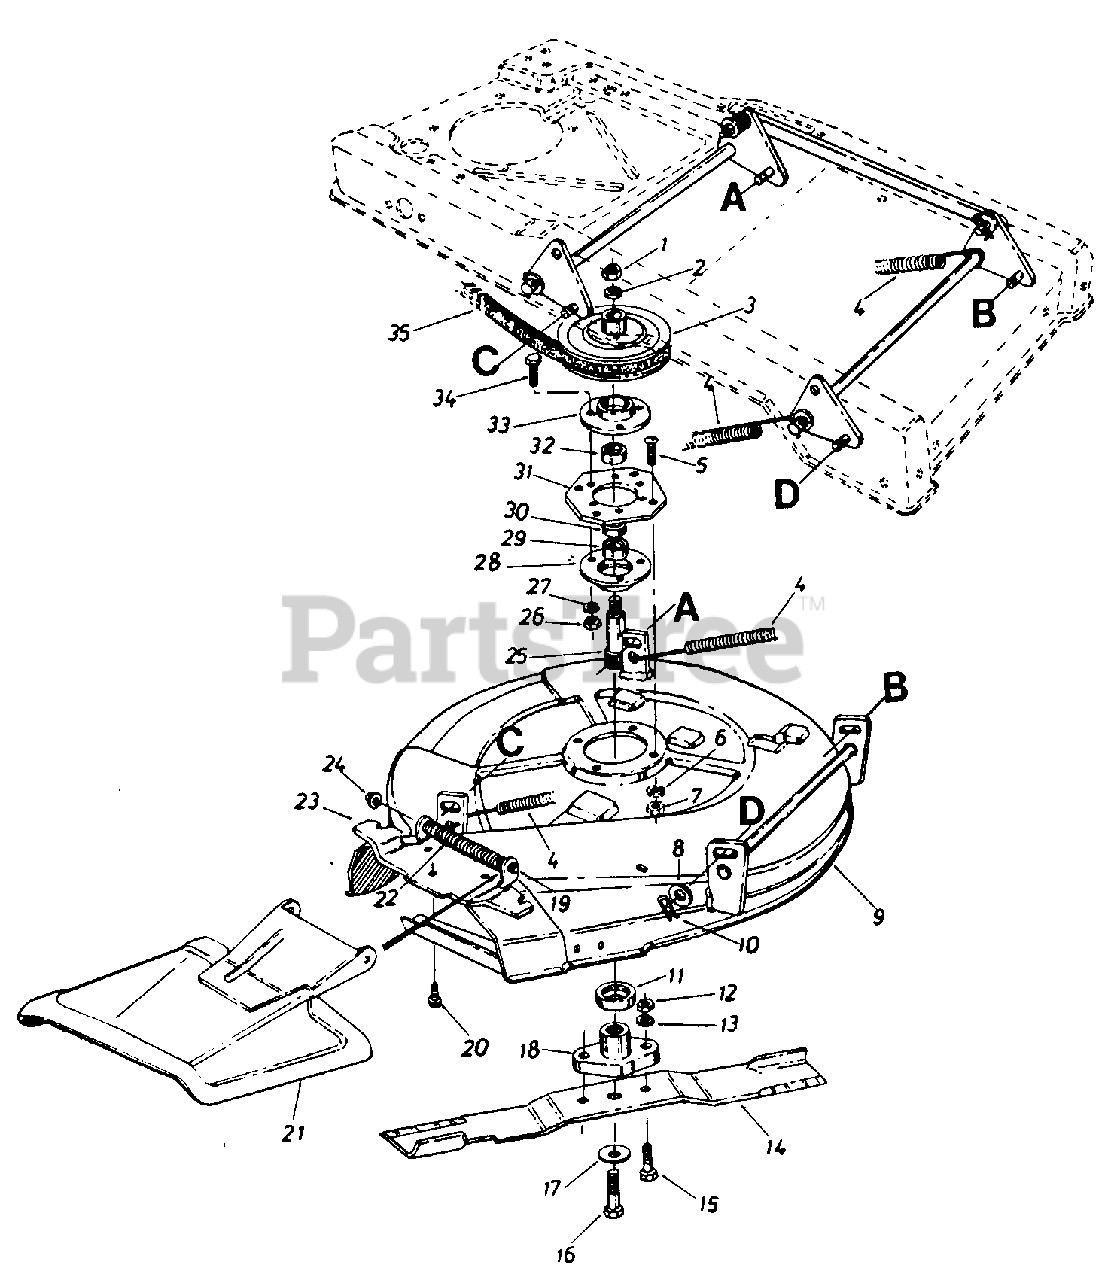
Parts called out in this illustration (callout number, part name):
1	NUT-HEX JAM 5/8-18
2	WASHER-BELL
4	SPRING-EXTENSION
5	SCREW-HEX 5/16-18 X .75
6	WASHER-LOCK-5/16
7	NUT-HEX 5/16-18
8	WASHER-FL .510 X .995 X .060
9	DECK ASSEMBLY-26IN
10	PIN-INTERN COT-1/2 DIA
11	SHIELD-BRG
12	NUT-5/16-24
13	WASHER-LOCK-5/16
14	BLADE-26IN
15	SCREW-HEX SPECIAL 5/16-24X1.0
16	BOLT-3/8 NF X 1"GR5
17	WASHER-BELL .390 ID X 1.375 X .062
18	ADAPTER-BLADE
19	PIN-HINGE
20	SCREW-HEX WASH SF TAPP
21	COVER-CHUTE-COMP
22	SPRING-TORSION
23	ADAPTER
25	SPINDLE-BLADE
26	NUT-HEX 5/16-18
27	WASHER-LOCK-5/16
28	HOUSING-BRG
29	BEARING-BALL
31	PLATE-SPINDLE MTG
32	BEARING-BALL
33	HOUSING-BRG
34	SCREW-HEX 5/16-18 X .75
35	BELT-V 1/2 X 62
